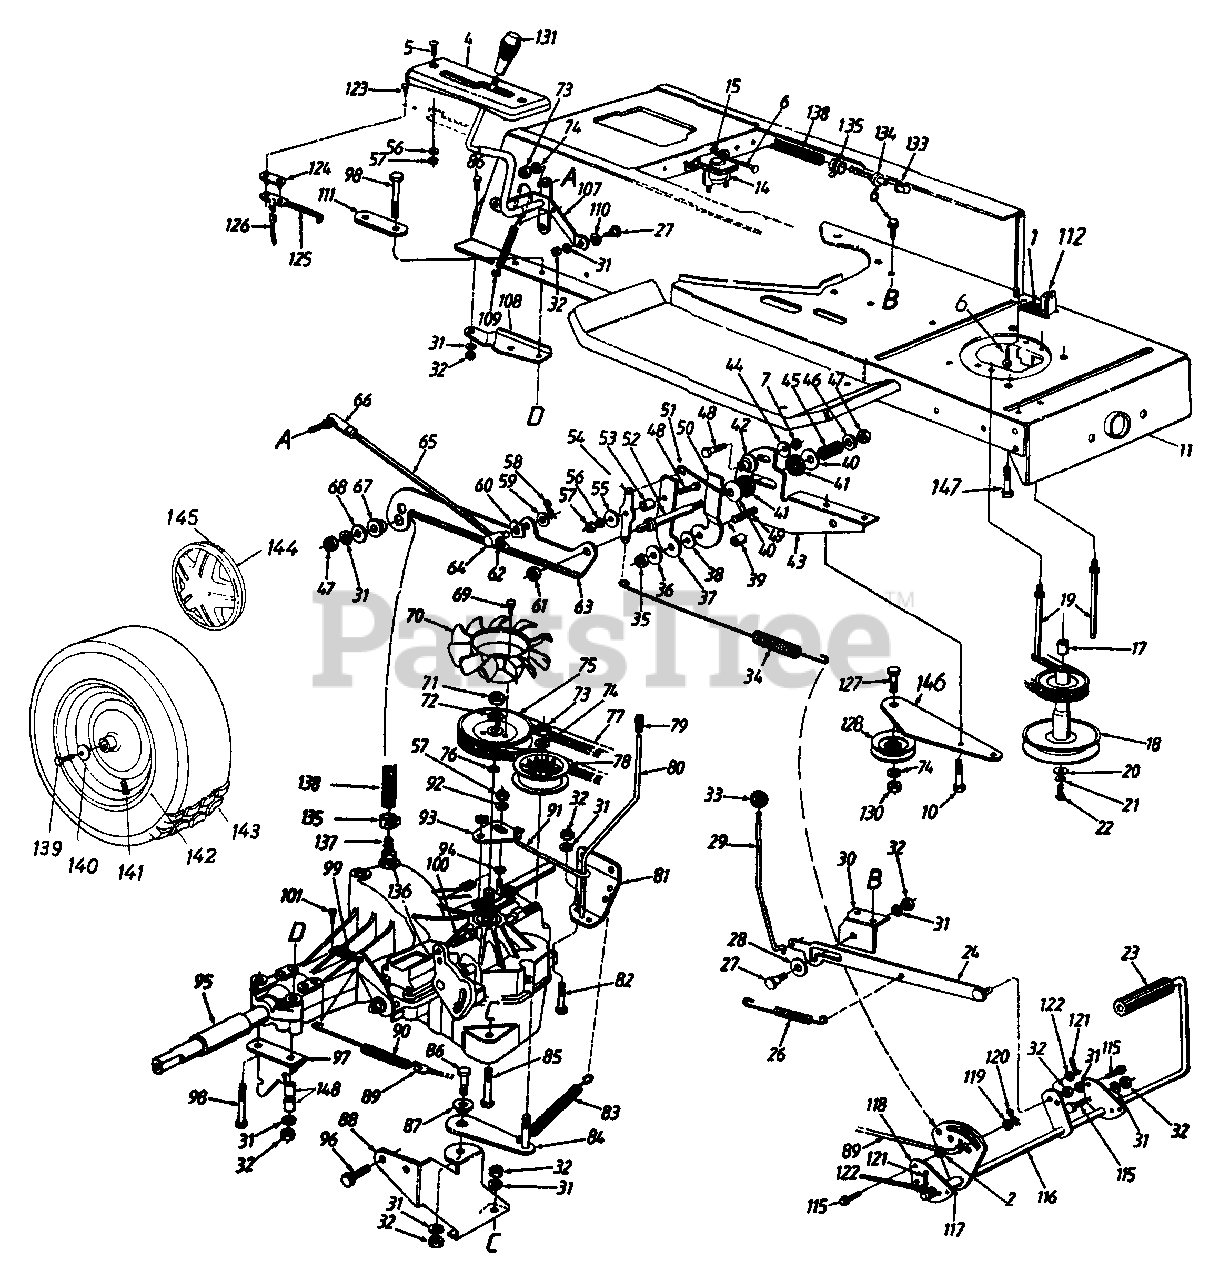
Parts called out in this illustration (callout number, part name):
1	Spring Switch
2	Hex Sems Nut 5/16-18 Thd.
4	Index Bracket
5	Pan Hd. Mach. Scr. 1/4-20 x .75" Lg.
6	Hex Wash. Hd. TT-Tap Scr. 1/4-20 x .5" Lg.
7	Hex Nut 1/4-28 Thd.
10	Hex . Bolt 1/4-28 x .62" Lg.
14	Solenoid
15	Ext. L-Wash. 1/4" I.D.
17	Spacer
18	Engine Pulley
19	Belt Guard Stud 4.75" Lg.
20	Fl-Wash. 7/16" I.D. x 1.25" O.D.
21	L-Wash. 7/16" I.D.
22	Hex Bolt 7/16-20 x 1.5" Lg.
23	Foot Pad
27	Shld. Bolt .437" Dia. x .268"
28	Fl-Wash. 7/16" I.D. x 1-3/8" O.D.
29	Lock-up Rod
30	Bracket
31	L-Wash. 5/16" I.D.
32	Hex Nut 5/16-18 Thd.
33	Ball Knob
34	Neutral Return Spring
35	Hex Nut 5/16-24 Thd.
36	Fl-Wash. .344" I.D. x 1" O.D.
37	Scissor-Flat
38	Fl-Wash. .33" I.D. x 1.25" O.D.
39	Spacer
40	Bell-Wash. .4" I.D. x 1.13" O.D.
41	Friction Washer
42	Centering Gauge Spacer
43	Neutral Return Mtg. Brkt.
44	Bell-Wash. .265" I.D. x .75" O.D.
45	Comp. Spring 1.19" Lg.
46	Fl-Wash. .26" I.D. x .72" O.D.
47	Hex Nut 5/16-24 Thd.
48	Hex Bolt 1/4-28 x 1" Lg. (Gr. 5)
49	Rib Neck Bolt 5/16-24 x .84" Lg.
50	Scissor-Offset
51	Neutral Return Rod
52	Friction Disc Stud
52	Hex Jam Nut 3/8-24 Thd.
53	Shld. Spacer
53	Neutral Return Brkt.
54	Neutral Return Lever
55	Fl-Wash. .265" I.D. x 1" O.D.
56	L-Wash. 1/4" I.D.
57	Hex Nut 1/4-20 Thd.
58	Hairpin Clip
59	Fl-Wash. .375" I.D. x .87" O.D.
60	Spring Wash. .39" I.D.
61	Hex L-Nut 3/8-24 Thd.
64	Ferrule 3/8-24 Thd.
65	Control Rod
66	Ball Joint 3/8-24 Thd
67	Shld. Spacer .5" Dia. x .27" Lg.
68	Fl-Wash. .349" I.D. x .879" O.D.
69	Hex Tap Scr #12 x 3/8" Lg.
70	Fan
71	Hex Nut 1/2-20 Thd.
72	L-Wash 1/2" I.D.
73	Hex Nut 3/8-24 Thd.
74	L-Wash 3/8" I.D.
75	Transmission Pulley
76	Wire Ring
77	"V"-Belt
78	Fl-Idler Pulley 2.75" O.D.
79	Rod End Grip
80	Bypass Control Lever
83	Ext. Spring 6.12
86	Hex Bolt 5/16-18 x .75" Lg.
87	Shld. Spacer .5" Dia x .27" Lg.
90	Ext. Spring
91	Bypass Actuator Rod
92	Fl-Wash. .281" I.D. x .5" O.D
93	Bypass Adjustment Brkt.
94	External L-Wash 1/4" I.D.
95	Sleeve .758" I.D. x 1" O.D.
96	Hex . TT-Tap Scr 5/16-18 x .62"
99	Tension Spring
100	Hex Bolt 5/16-24 x 1" Lg. (Special)
101	Hex Wash. Hd AB-Tap Scr #10 x .5" Lg.
107	Speed Control Lever Ass'y.
110	Spr-Wash. .445" I.D. x .75" O.D.
112	Safety Switch (Clutch)
115	Hex TT-Tap Scr 5/16-18 x .75"
120	Cotter Pin 3/32" Dia.
121	Cotter Pin 1/8" Dia
122	Fl-Wash...385" I.D. x .62" O.D
123	Hex AB-Tap Scr. #8 x .5" Lg.
124	Insulator Nut Plate
125	Reverse Safety Switch
126	Extension Wire
127	Hex Bolt 3/8-16 x 1.5" Lg.
128	Idler Pulley
130	Hex Nut 3/8-16 Thd.
131	Shift Knob
133	Vent Cap
134	Plastic Vent
135	Clamp
136	"O"-Ring
137	Hose Fltting
138	Fuel Line 18" Lg.
139	Hex Bolt 5/16-24 x .75" Lg.
140	Bell-Wash. .345" I.D. x .88" O.D.
141	Air Valve
142	Rim Only
143	Wheel Ass'y. Comp.
144	Hub Cap (Gray)
145	Spring Clip
148	Spacer .32" I.D. x .75" O.D.
